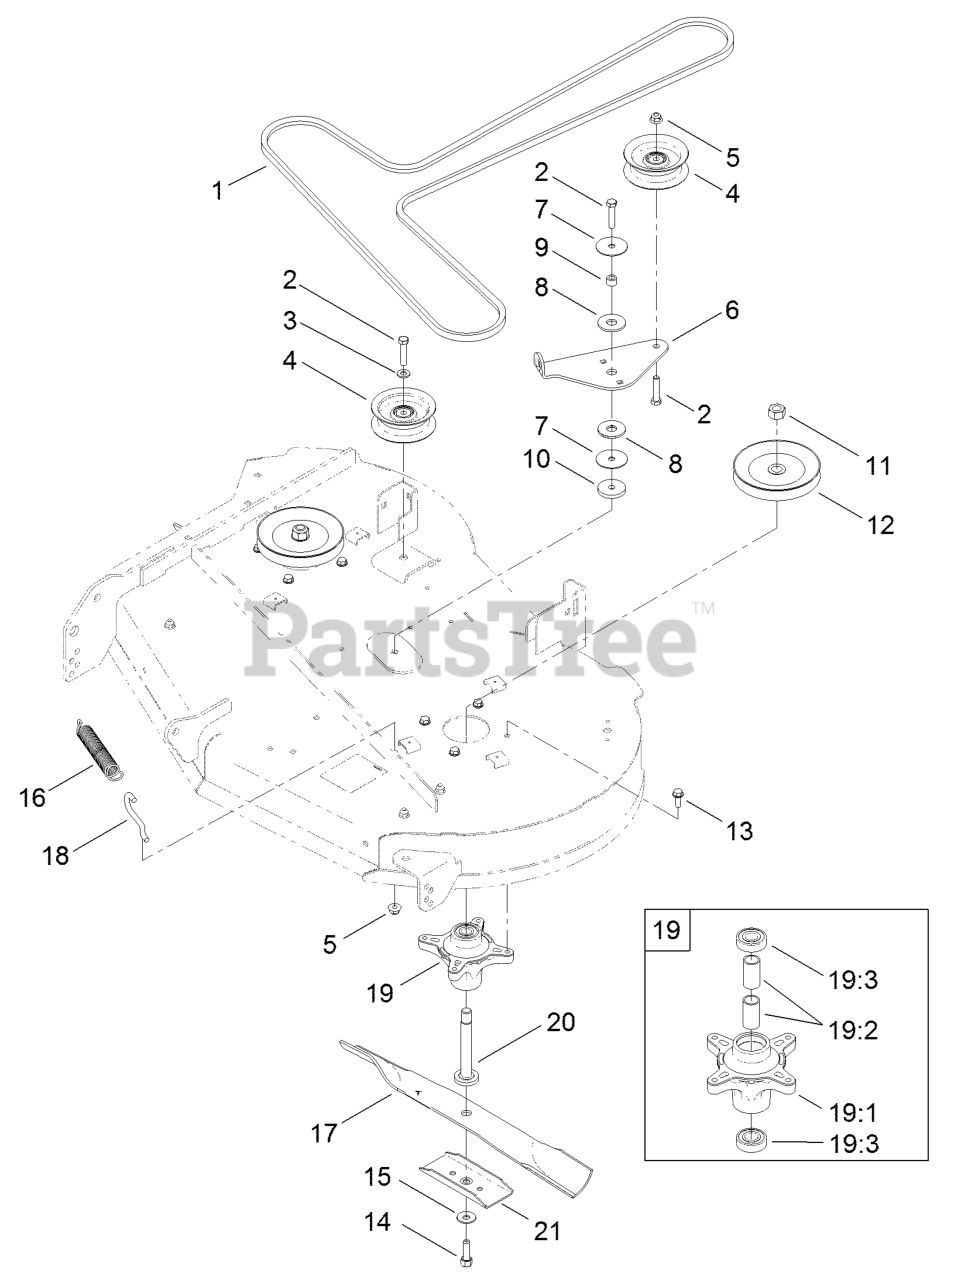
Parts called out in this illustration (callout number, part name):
1	V-BELT
2	SCREW-HH
3	WASHER-FLAT
5	NUT-HF, NI
6	ARM-IDLER
8	WASHER-FRICTION, COMPOSIT
10	SCREW-HH
11	NUT-HEX
12	PULLEY
13	SCREW-TAPTITE
14	SCREW-HH
15	WASHER-BELLEVILLE
16	SPRING-EXTENSION
17	BLADE-21.6 INCH
18	HOOK-RETURN, SPRING
19	SPINDLE ASM
20	SHAFT-SPINDLE
21	STIFFENER-BLADE
